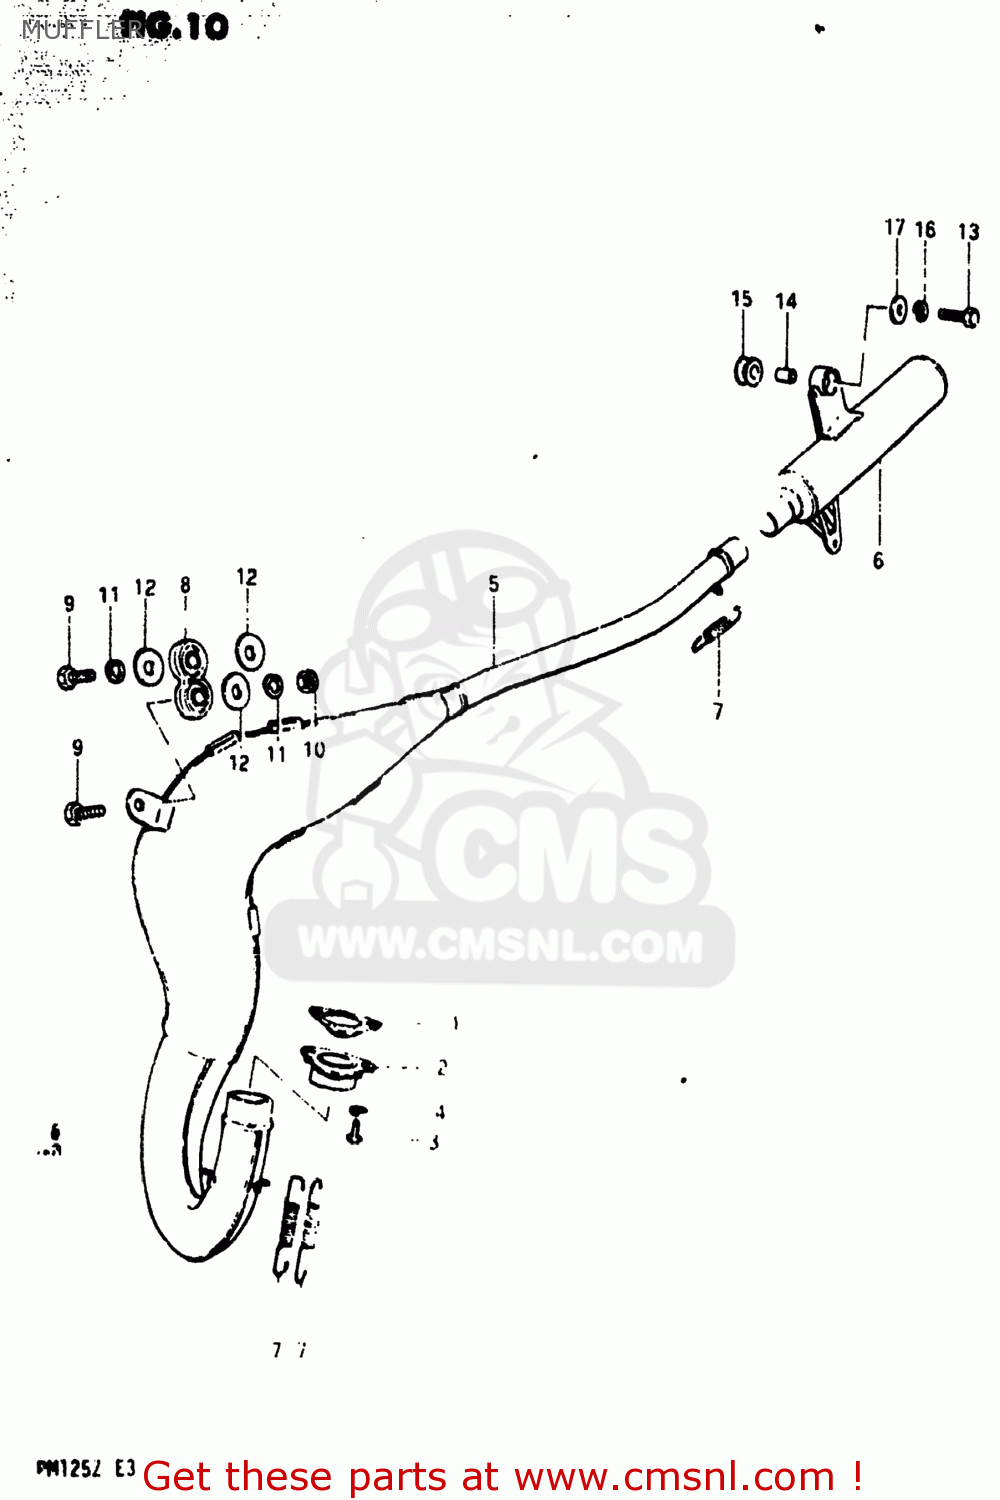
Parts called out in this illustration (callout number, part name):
1	GASKET,EXHAUST PIPE (MCA)
2	FLANGE,EXHAUST PIPE
3	SCREW
4	LOCK WASHER
5	BODY,MUFFLER
6	BODY,MUFFLER
7	SPRING
8	DAMPER,MUFFLER
9	BOLT(8X32)
10	NUT 8MM
11	LOCK WASHER
12	WASHER
13	BOLT(8X32)
14	SPACER (8.6X12X17.5)
15	CUSHION
16	LOCK WASHER
17	WASHER (8.5X29X1.6)
